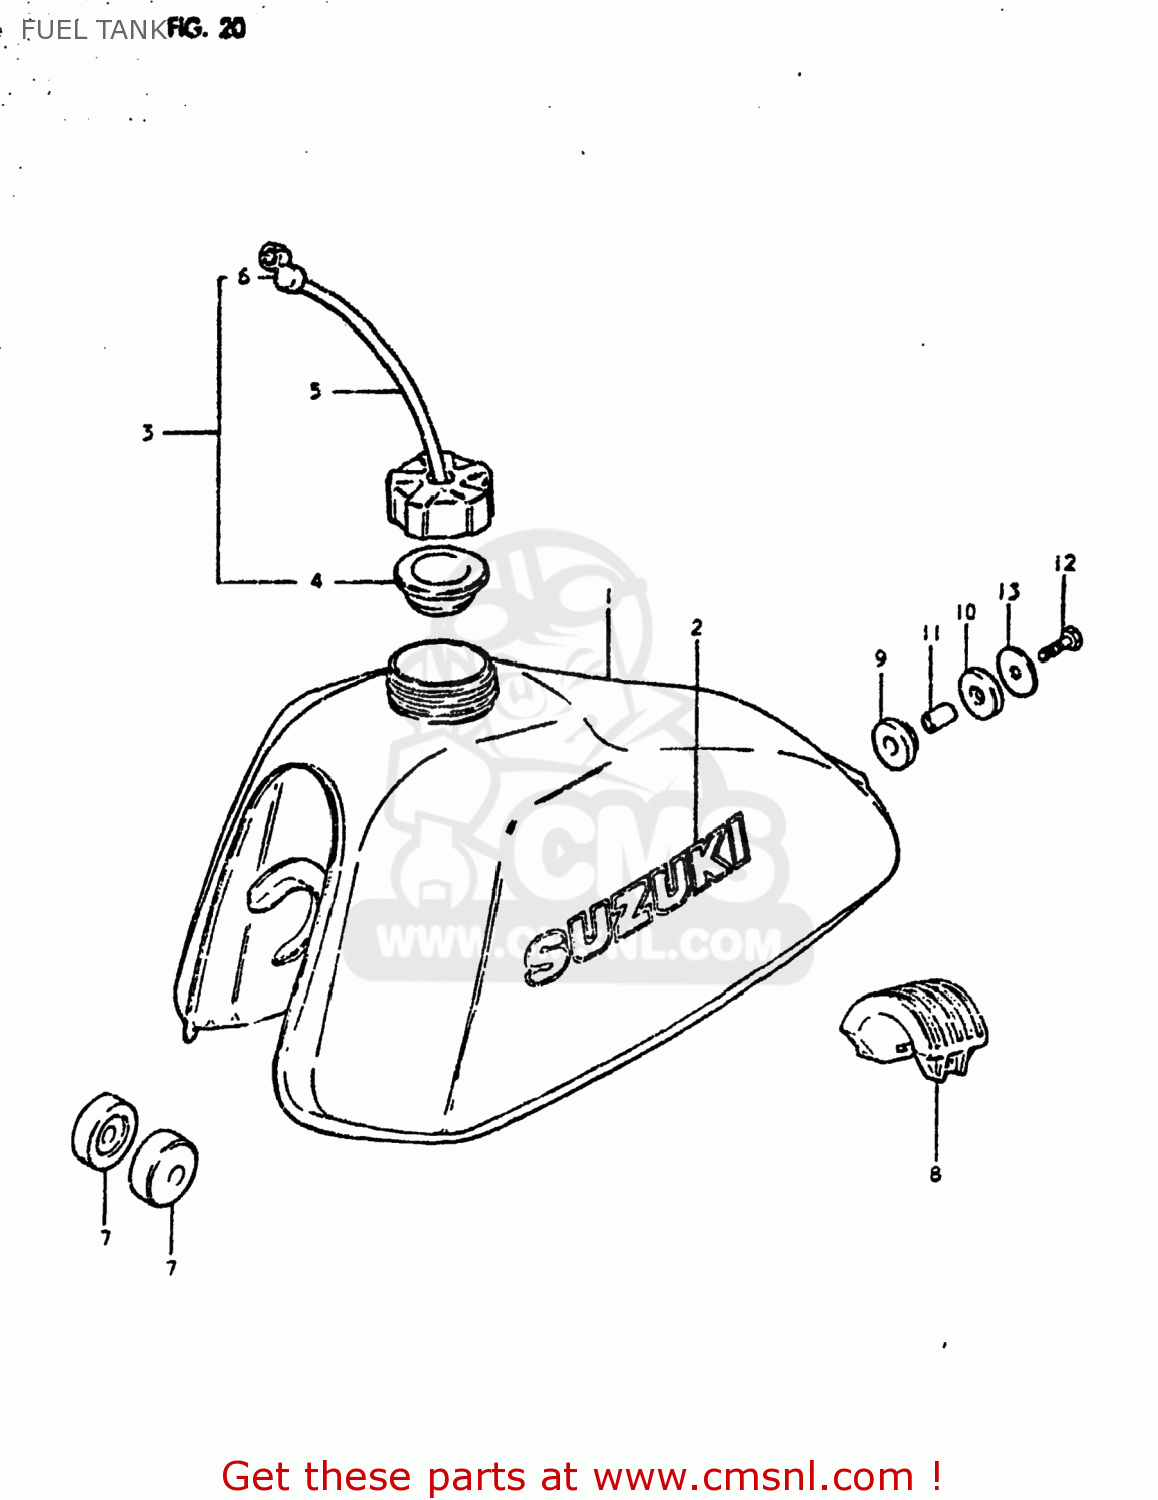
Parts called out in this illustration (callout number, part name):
1	TANK ASSEMBLY,FUEL
2	EMBLEM,FUEL TANK(WHITE)
3	CAP SET,FUEL TANK
4	GASKET,FUEL TANK CAP (NAS)
5	HOSE
6	CLAMP,FUEL TANK BREATHER HOSE
7	CUSHION
8	CUSHION,FUEL TANK
9	CUSHION
10	CUSHION
11	SPACER (8.2X12X17)
12	BOLT (8X30)
13	WASHER (8.5X29X1.6)
